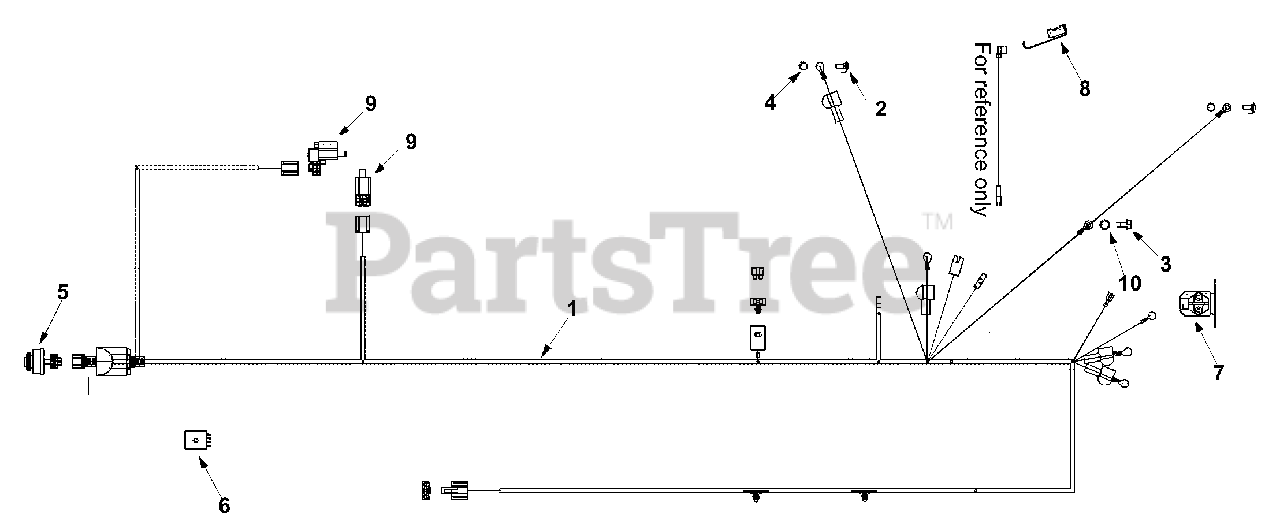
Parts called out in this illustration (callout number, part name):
1	Harness Assembly w/o relays
2	Carriage Screw 1/4-20 x 0.62"
3	D Screw 5/16-18 x 0.625"
4	Sems Nut 1/4-20
5	Ignition Switch: 5 Pin
6	Seat Switch
7	Solenoid 12 volt, 100 amp.
8	Spring Switch
9	Switch: Interlock
10	Lock Washer 5/16
